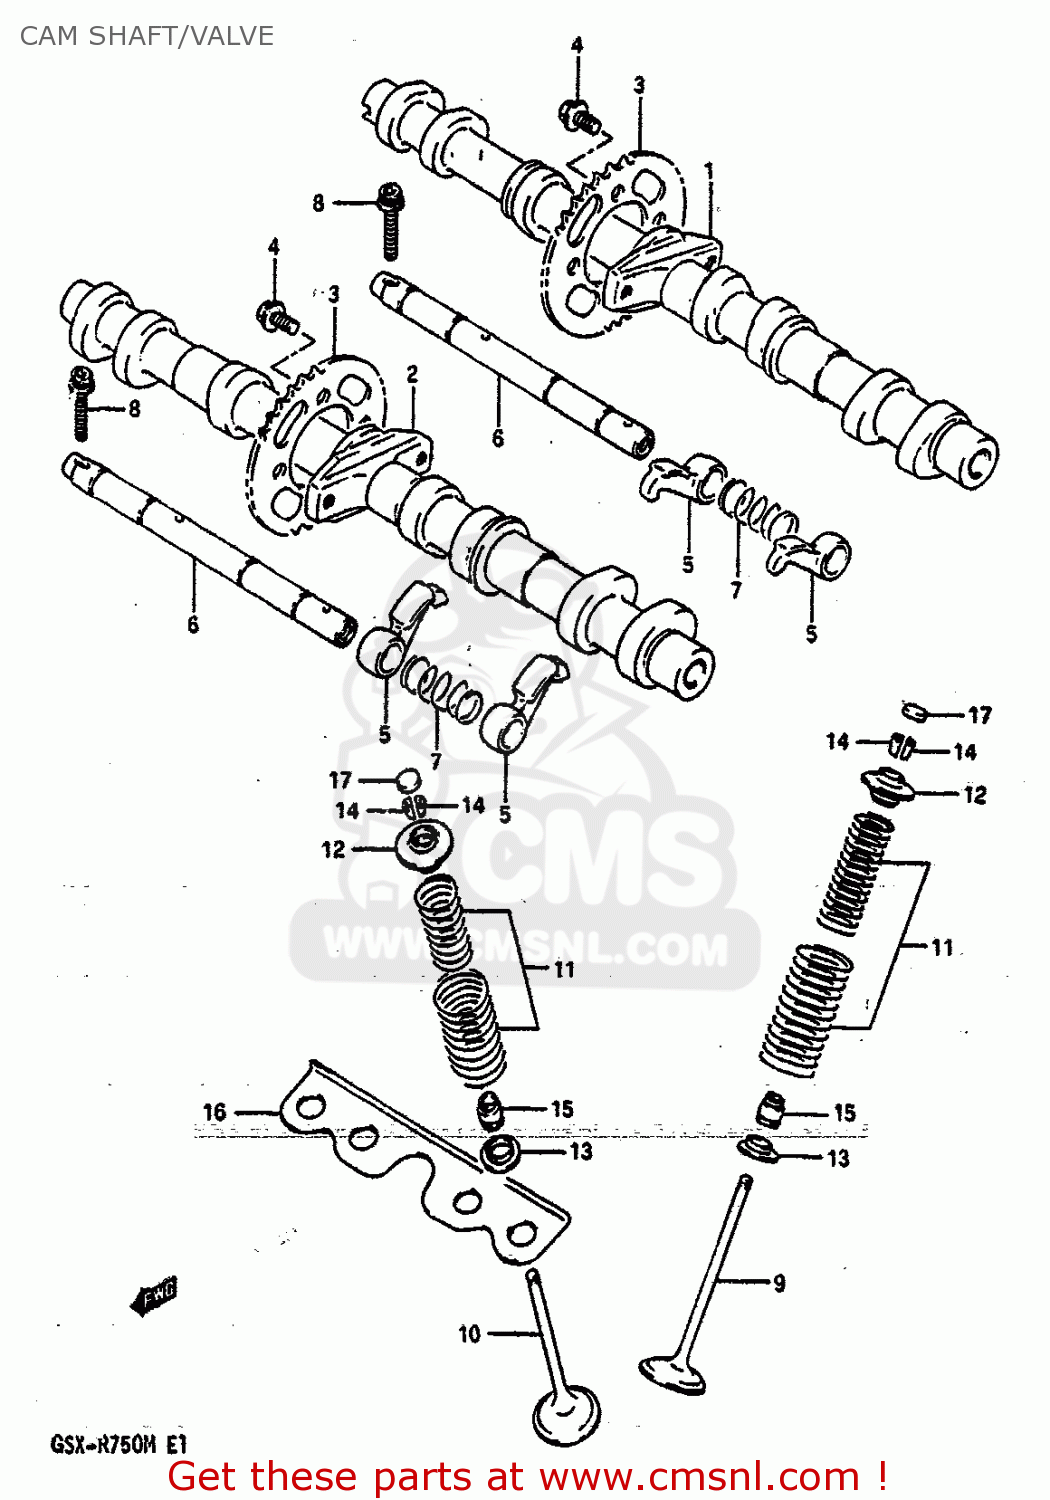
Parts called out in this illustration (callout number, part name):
1	CAMSHAFT,INTAKE
2	CAMSHAFT,EXHAUST
3	SPROCKET,CAMSHAFT
4	BOLT(7X11)
5	ARM,VALVE ROCKER
6	SHAFT,VALVE ROCKER
7	SPRING
8	BOLT
9	VALVE,INTAKE
10	VALVE,EXHAUST
11	SPRING SET,VALVE
12	RETAINER,VALVE SPRING
13	SEAT,VALVE SPRING
14	COTTER VALVE
15	SEAL,OIL(5X10X9.7)
16	PLATE
17	SHIM,TAPPET(T:2.5)
19	CASE,TAPPET SHIM
